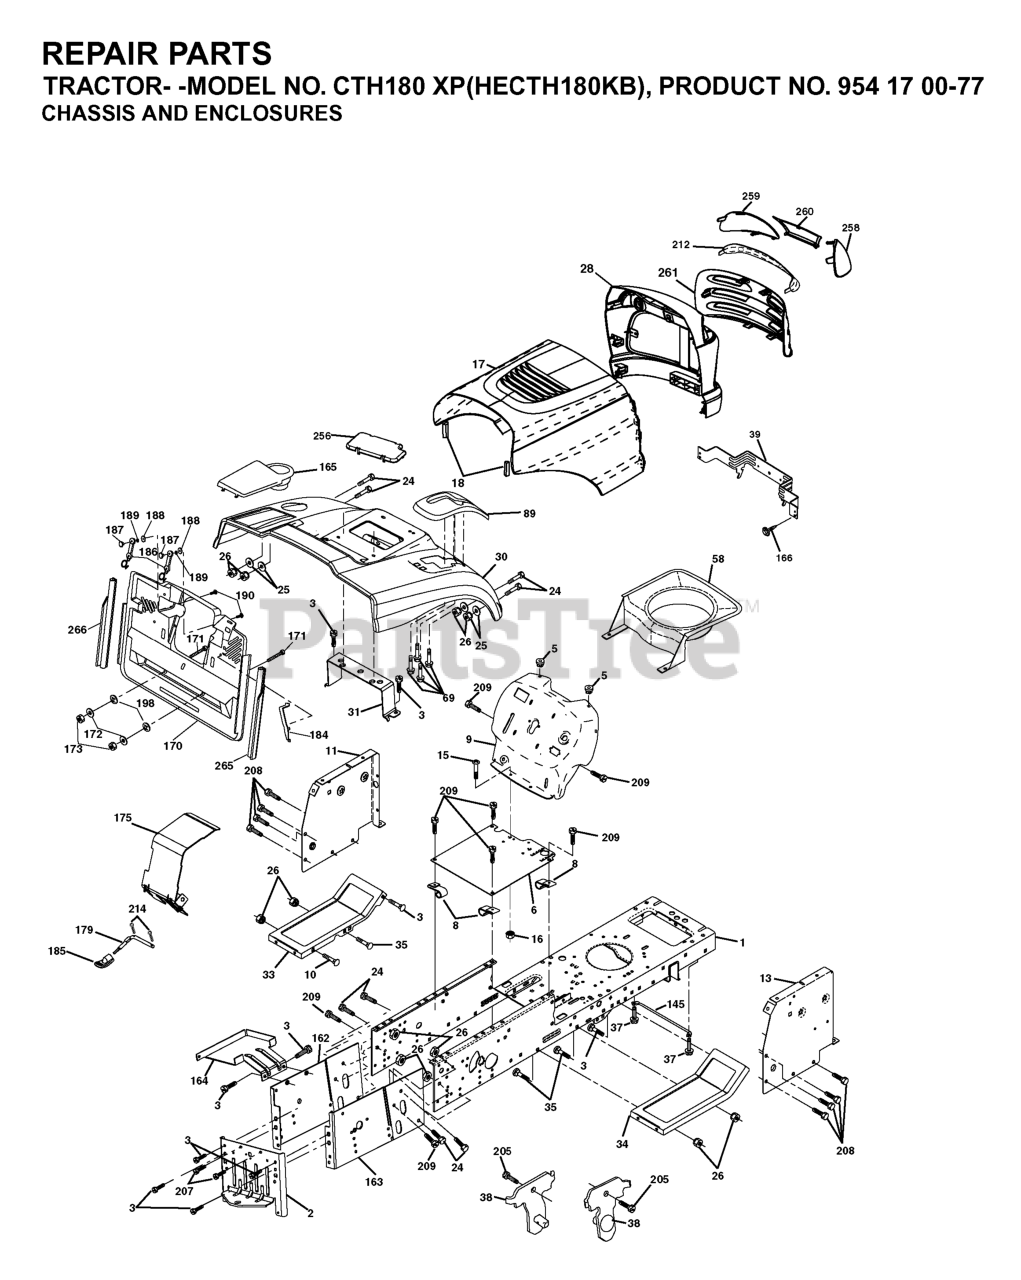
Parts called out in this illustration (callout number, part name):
2	DRAWBAR
3	SCREW 3/8-16X3/4
5	BUMPER.RUBBER.HOOD
6	PLATE
8	CLIP,INSULATOR
10	BOLT D
11	PANEL.DASH.LH.LTX
13	PANEL ASM, DASH RH
15	Screw, Machine, Truss Head 5/16-18 UNC x 3/4
16	NUT
17	HOOD
18	BUMPER.HOOD.LARGE.1.75"
20	PLATE MTG.BATTERY/FUEL TANK
25	WASHER
26	NUT
31	BRACKET SUPPORT FENDER
33	FOOTREST PNT LH
34	FOOTREST PNT RH
37	Screw 5/16-18 x 1/2 Hex, Self Tapping 5/16-18 x 1/2
38	BRACKET ASM PIVOT MOWER REAR
39	BRACKET PIVOT LASER
69	SCREW.HI-LO.CONSOLE
89	COVER.BATTERY.CRD.GREY
145	ROD PIVOT CHASSIS/HOOD
162	BRACKET
163	BRACKET EXTEN CHASSIS RH CRD
165	RP.COVER.BATTERY.CRD.GREY
166	SCREW
172	WASHER
184	BRACKET.ACTUATOR.BAGGER.SRD
186	LATCH ASSY
187	WELDNUT
189	LOCKWASHER #10
190	SCREW
207	SCREW, 5/16-18 X 1/2
208	SCREW 3/8-16X1/2
209	SCREW, 3/8-16X3/4
212	INSERT.LENS.REFLECTIVE
214	RETAINER M
219	SCREW
256	COVER FENDER CRD
258	LENS LH
259	LENS LH
260	COVER.LENS.HUSQ.LASER
265	SEALING
266	SEALING
